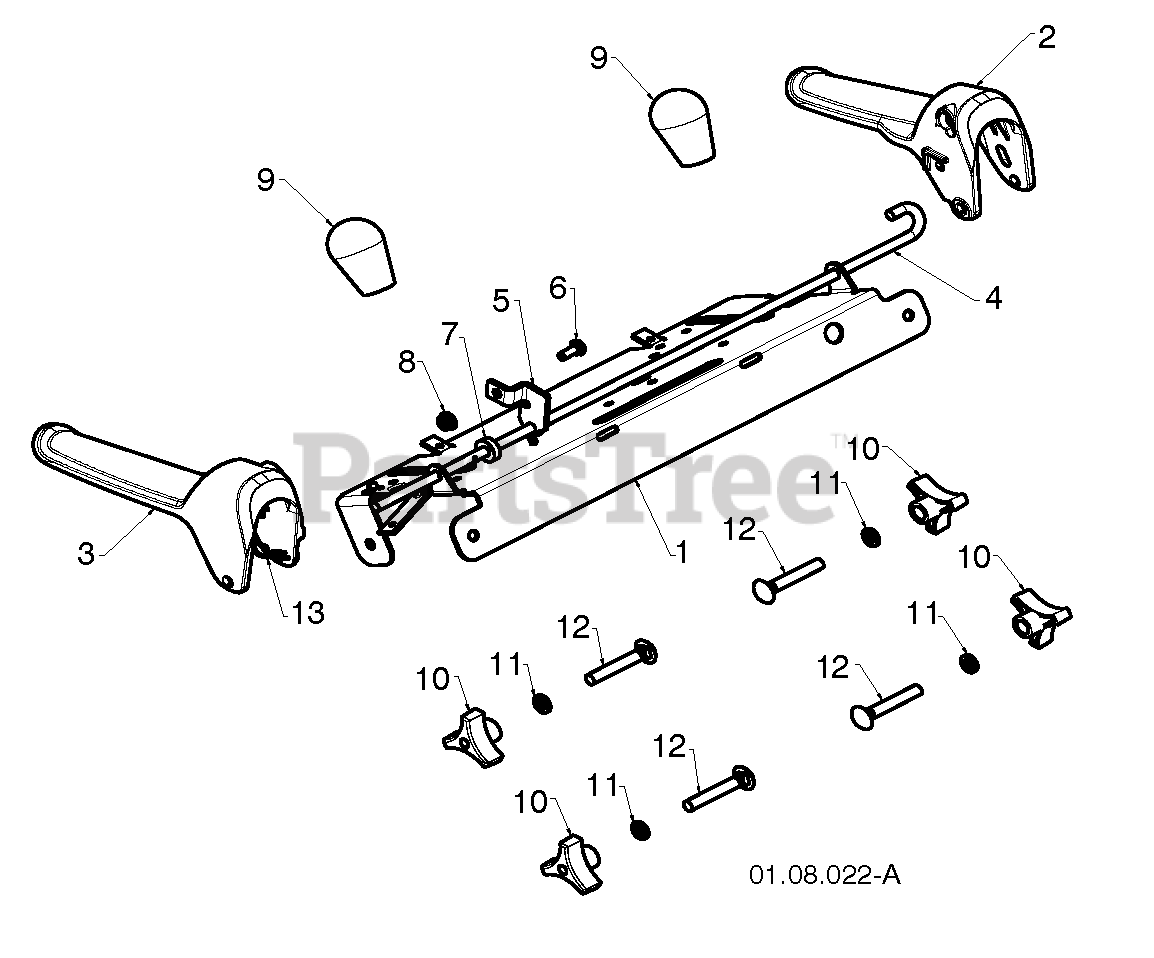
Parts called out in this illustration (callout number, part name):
1	PANEL.CONTROL.SNOW.BLACK
3	LEVER.CONTROL.RH.PL.BLACK
4	BAIL.CONTROL.INTERLOCK.SNOW
5	BRACKET.ARM.IMPELLER.ROD.YZ
6	BOLT
7	SPACER.CONTROL.LEVER
9	KNOB.OVERMOLD.DS.HUSQVARNA/BLK
10	KNOB.HANDLE.3/8.TRI-POINT.BLAC
11	WASHER
12	BOLT 3/8-16 X 2-1/4
13	SPRING RETAINER
